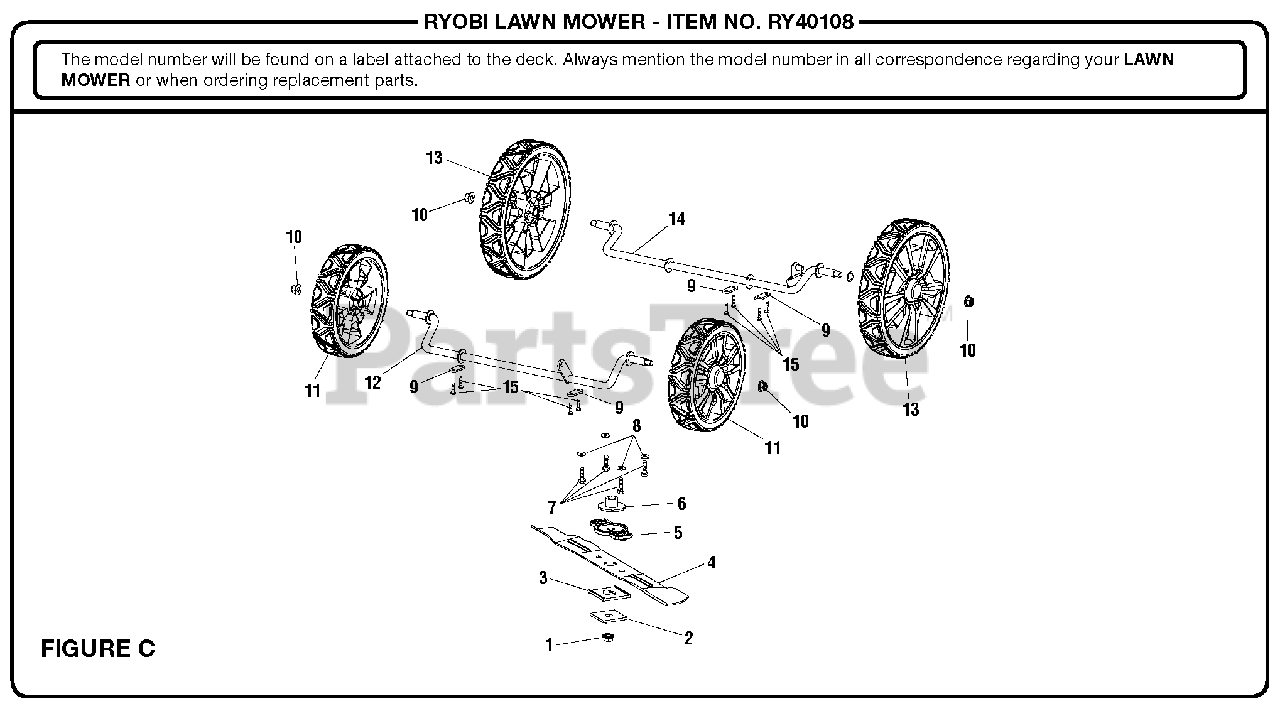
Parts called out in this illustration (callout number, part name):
1	Hex Nut (M10, Flange)
2	Blade Retainer
4	Blade
5	Blade Holder
6	Motor Shaft Bushing
7	Bolt (M6 x 26 mm, Hex Hd.)
8	Washer (ID6.2 x OD15 x 0.08t)
9	Axle Pressure Plate
10	Lock Nut (3/8-16, Flange)
11	Front Wheel Assembly
12	Front Wheel Axle
13	Rear Wheel Assembly
14	Rear Wheel Axle
15	Screw (M4 x 20 mm, T20 Torx Pan Hd.)
